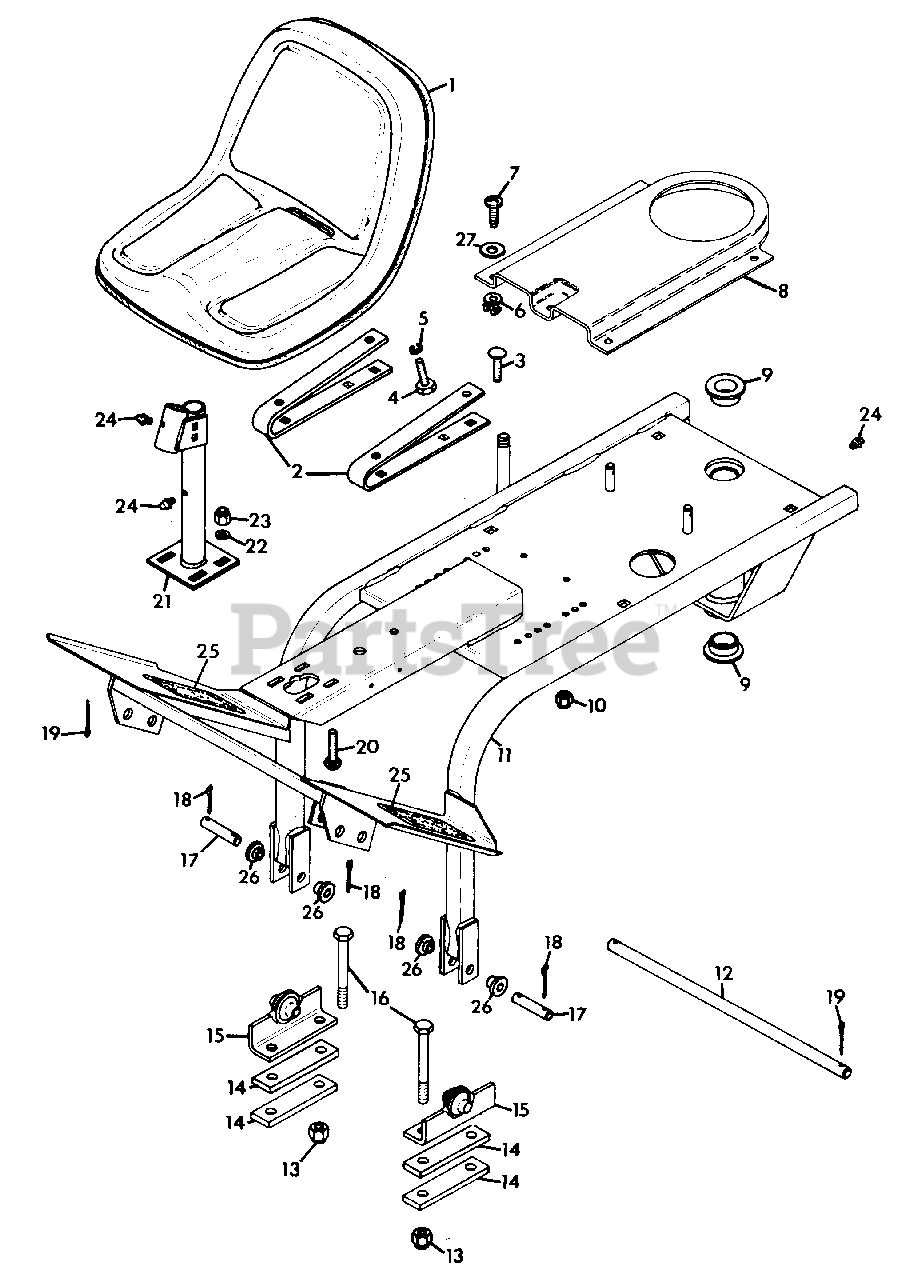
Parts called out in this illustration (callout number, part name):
1	SEAT, HIGH BACK
2	SPRING, SEAT
3	BOLT, 5/16-18X1.00 RD HD SQ NK
4	BOLT, HEX 5/16-18X.75
5	WASHER, LOCK 5/16
6	GROMMET, PLASTIC
7	SCREW, 1/4-20X.625
8	COVER, CHAIN
9	BEARING, FLANGED
10	NUT, LOCK 5/16-18
11	FRAME, O.F.C.
12	SHAFT, BRAKE
13	NUT, LOCK 1/2-13
14	PLATE, AXLE
15	BRACKET, MOUNT
16	BOLT, HEX 1/2-13X5.50
17	PIN, .750X3.3
18	PIN, COTTER .125X1.500
19	PIN, COTTER .125X1.25
20	BOLT, 3/8-16X1.00 RD HD SQ NK
21	TUBE, STEERING
22	WASHER, FLAT .406X.812X.065
23	NUT, LOCK 3/8-16
24	FITTING, LUBE 1/4-28
25	COVER, LARGE FOOTBOARD
26	BUSHING
27	WASHER, FLAT .344X.688X.065
NS	DECAL, GRAVELY LOGO
NS	DECAL, PRO MASTER-50
